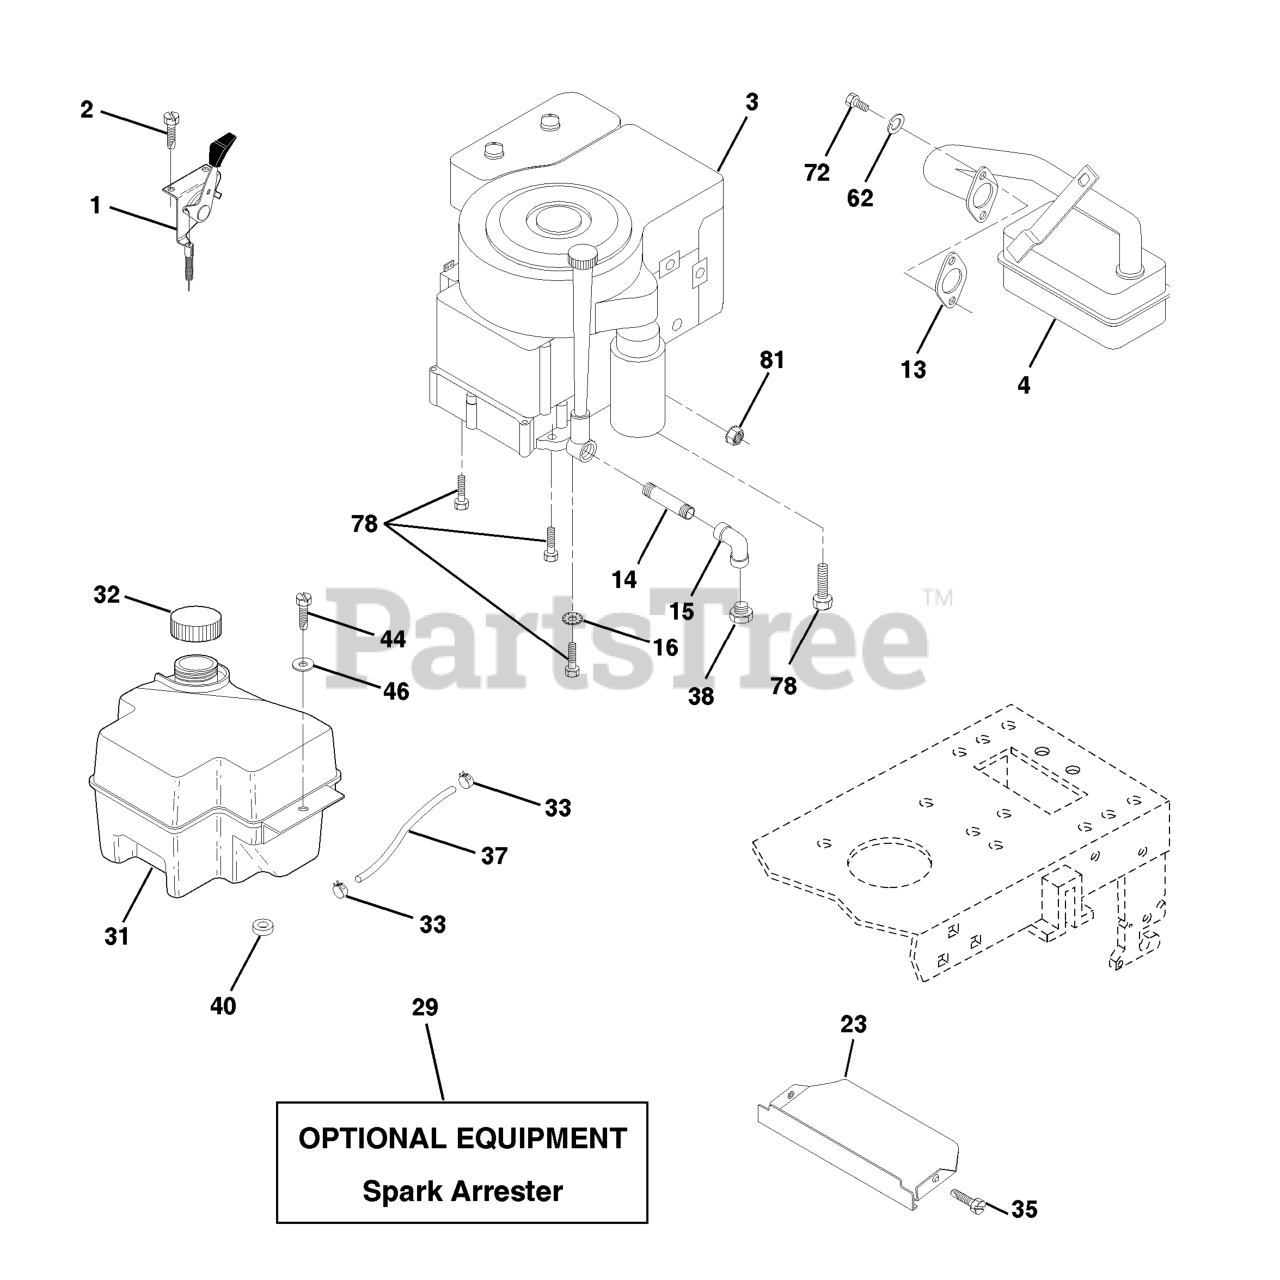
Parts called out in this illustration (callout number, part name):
1	CHOKE CONTROL
2	SCREW LT
4	MUFFLER.SINGLE.B&S.10-12HP
13	GASKET.ENG.1.313 ID.TIN PLATED
14	Nipple Pipe 3/8 Npt X 3"
15	ELBOW
16	LOCKWASHER
29	KIT.SPARK ARRESTOR 794945 B&S
31	FUEL TANK
32	FUEL CAP
33	HOSE CLAMP
35	SCREW.THDROL.5/16-18X3/4.TTY
37	LINE.FUEL.20
38	Plug Oil Drain
40	BUSHING.SNAP.NYL.BLK.
44	SCREW HEX CRT
46	WASHER
62	WASHER.LOCK.HVY.HLCL.SPR.5/16
72	SCREW
78	SCREW
81	NUT FLANGE 1/4-20 STARTER NUT
